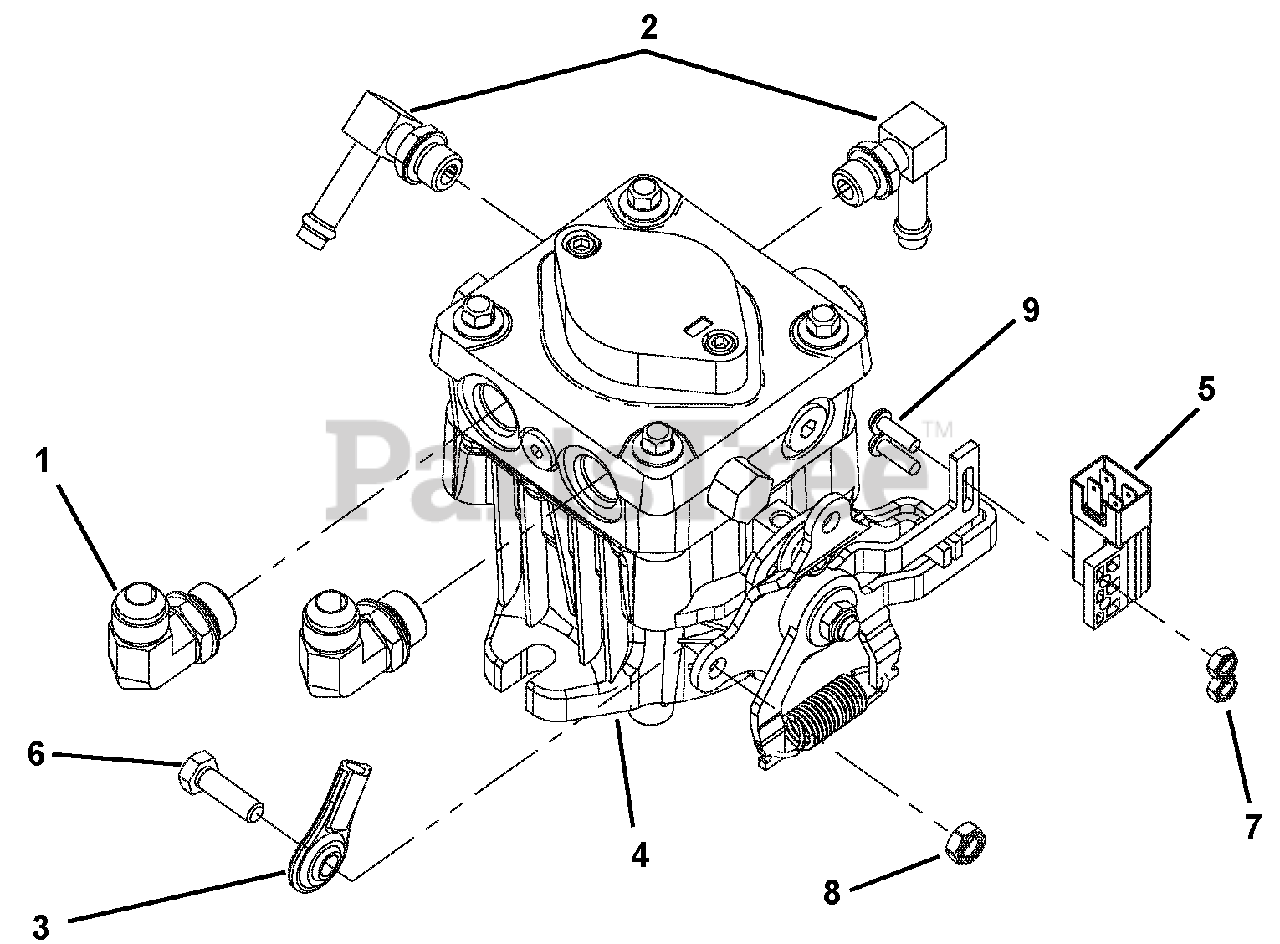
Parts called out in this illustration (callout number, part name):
1	FITTING, INCLUDES O-RING
2	FTG-ADPTR .562-18 ST THD
3	ROD END, 5/16 RH - FEMALE
4	PUMP, LH
5	SWITCH, PLUNGER DP -N.O.-N.C.
6	@BLT-HEX .31-18X1.00 GR5 YWZC
7	@NUT-LK-NYL 10-24 W/INSRT YWZC
8	@NUT-LK-NYL .312-18 YWZC
9	SCR-MCH 10-24X.62 P/HD
NS	KIT, PUMP SEAL BDP10 & 12 S/O
